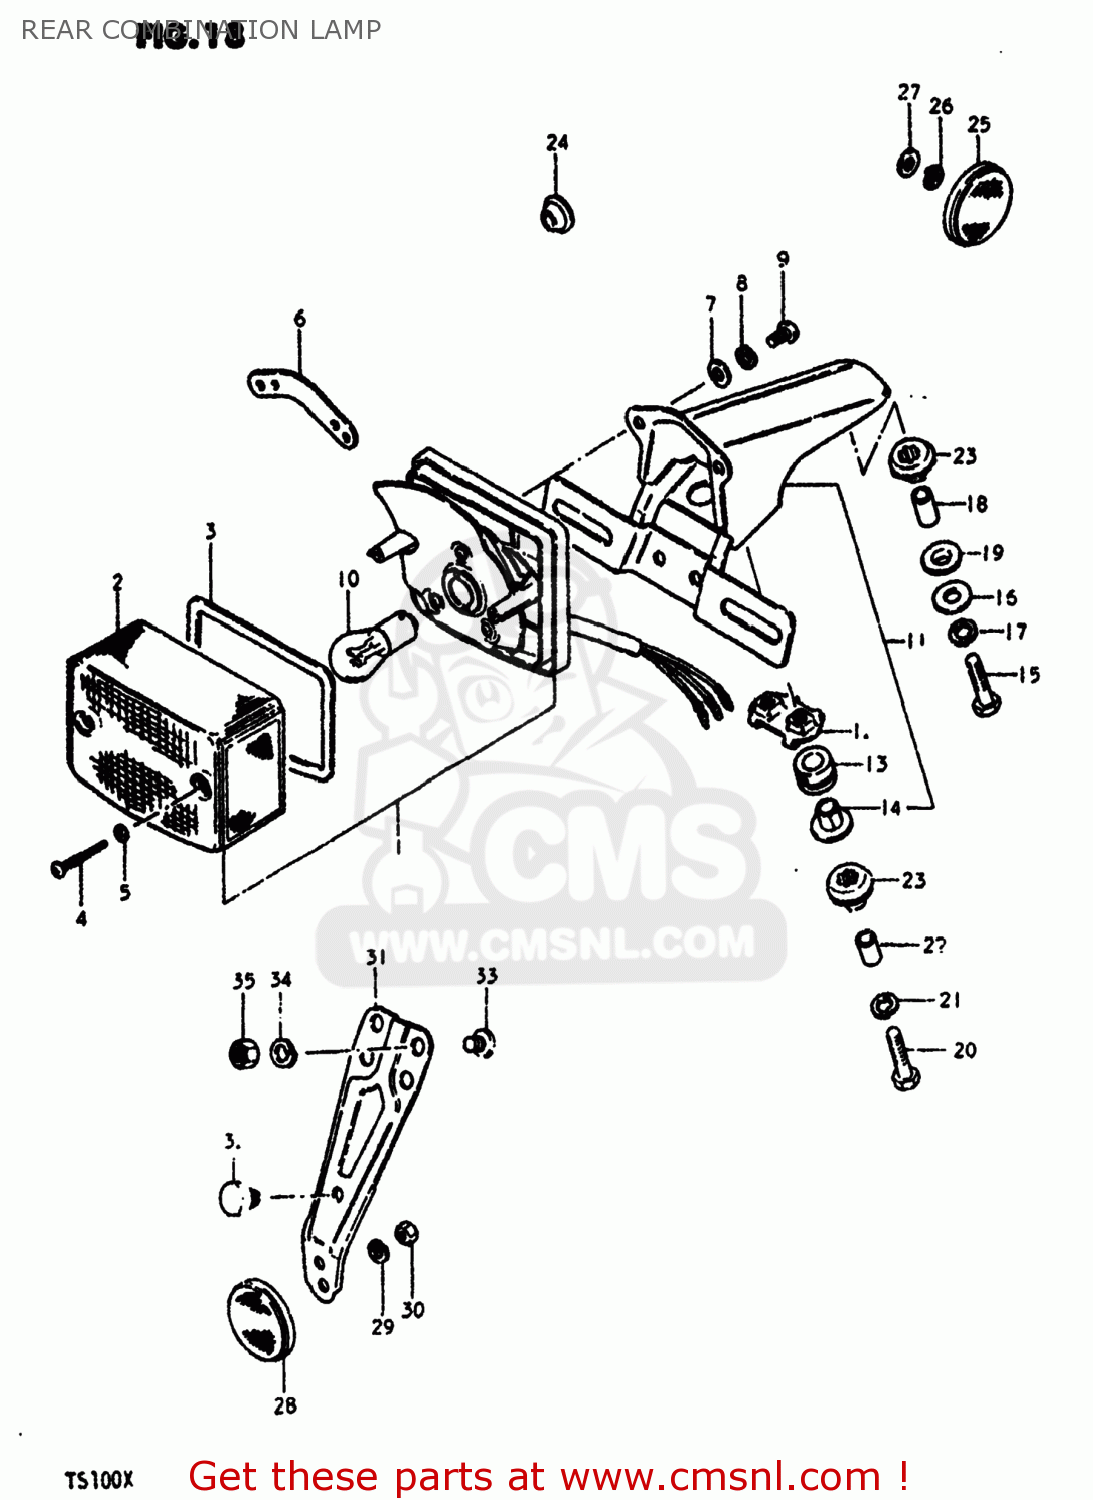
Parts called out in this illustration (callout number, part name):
1	LAMP UNIT,REAR COMBINATION
2	LENS
3	GASKET (NAS)
4	BOLT
5	GASKET (NAS)
6	PLATE,REAR COMBINATION LAMP
7	WASHER
8	LOCK WASHER
9	SCREW
10	BULB(6V32/3CP,STANLEY)
11	BRACKET UNIT,TAIL LAMP
12	PLATE
13	CUSHION
14	SPACER
15	BOLT
16	WASHER (6.5X20X1.2)
17	LOCK WASHER
18	SPACER
19	CUSHION
20	BOLT 6X40
21	LOCK WASHER
22	SPACER (6.8X10X11.5)
23	CUSHION
24	GROMMET
25	REFLEX REFLECTOR,FR
26	LOCK WASHER
27	WASHER
28	REFLEX REFLECTOR,RR
29	LOCK WASHER
30	NUT
31	BRACKET
32	CUSHION
33	SCREW
34	LOCK WASHER
35	NUT
